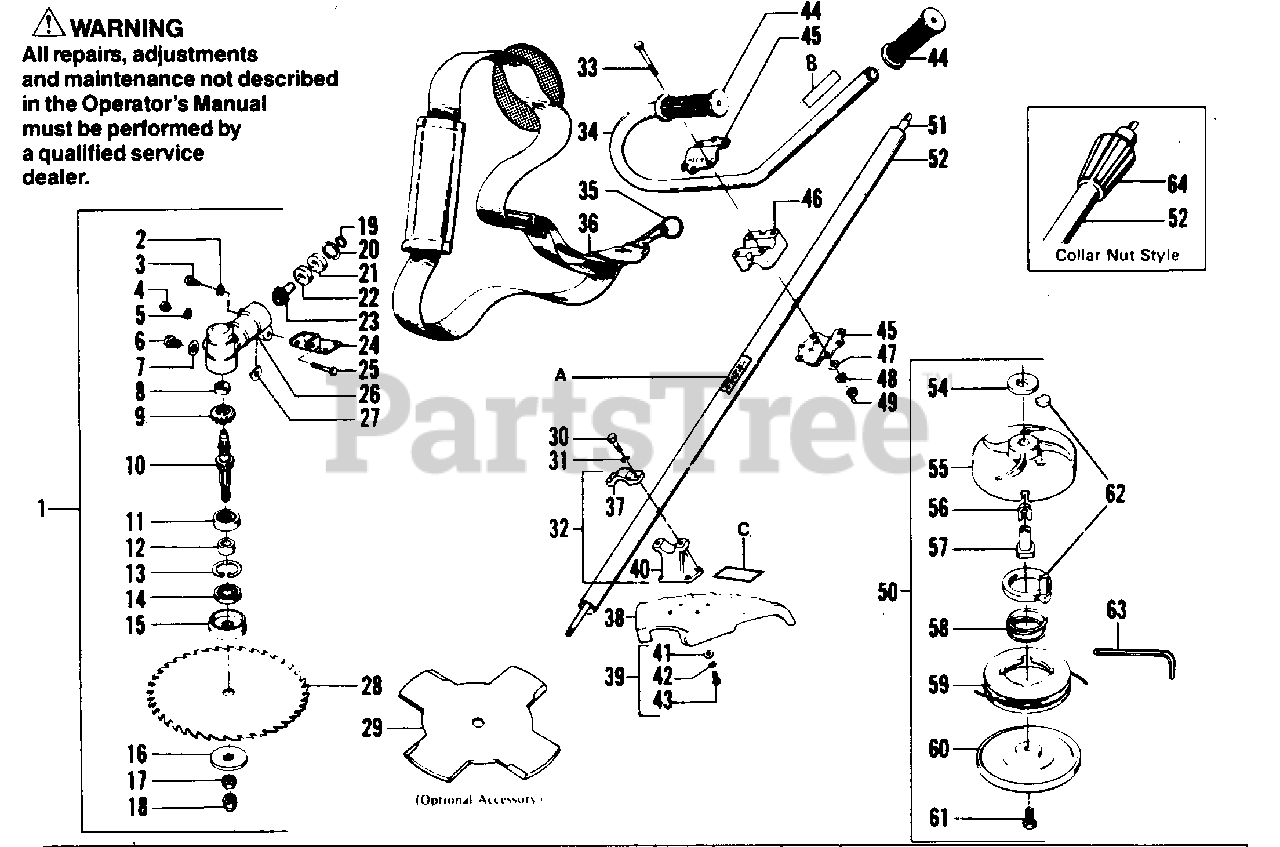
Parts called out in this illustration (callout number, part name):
1	Gear Box Ass'y w/fasteners (Inc. 2-27)
2	Lockwasher - Housing Bolt
3	Bolt - 6 x 12mm
4	Nut - 6mm - Housing (Gear Box)
5	Lockwasher - 6mm - Housing (Gear Box)
6	Oil Plug
8	Bearing - Gear Box
9	Gear - Bevel
10	Shaft - Splined Drive
11	Ball Bearing
12	Collar - Shaft
13	Snap Ring
14	Oil Seal
15	Blade Adaptor - Upper
16	Blade Adaptor - Lower
19	Snap Ring - Gear Housing
20	Snap Ring - Gear Housing Bearing
21	Bearing - Sealed Pinion Gear
22	Bearing - Pinion Gear
23	Pinion Gear
24	Bracket-Shield to Gear Box,See Service Ref. 1
25	Bolt 6 x 42mm - Housing (Gear Box)
26	Housing - Gear Box
27	Fiber - Filler Washer
28	10" Brush Blade
29	8" Weed Blade (Optional)
30	Bolt - 5 x 25mm
31	Washer - 5mm
32	Shield Mounting Bracket Ass'y (Inc. 37 & 40)
33	Bolt - #1/4 - 20 x 1 - 7/8" - Handlebar
34	Handlebar
35	Key Ring - Shoulder Strap
36	Shoulder Strap
37	Shield Mounting Bracket - Top
38	Shield w/fasteners
39	Shield Mounting Kit (Inc.41,42,43 - 4 each)
40	Shield Mounting Bracket - Bottom
41	Washer - 4mm - Flat
42	Lockwasher - 4mm
43	Screw - 4mm x 16mm
44	Grip - Handlebar
45	Handlebar Clamp
46	Handlebar Block
47	Washer - Handlebar
48	Lockwasher - Handlebar
49	Nut - #1/4 - 20
50	Cutting Head Assembly (Inc. 54-63)
51	Drive Shaft
52	48" Drive Shaft Housing w/bearings
52	Collar Nut Style (Inc.64)
52	Pinch Clamp Style
56	Line Saver
57	Drive Adaptor
59	Spool w/line
60	Cover - Cutting Head
61	Screw - #3/8 - 16 x 7/8" - Cover
62	Release Button Ass'y (Incl. Lock Ring)
63	Allen Wrench - Cutting Head
64	Collar Nut
A	Decal Handlebar Location
A	Model XR-90
A	Model XR-95,XR-100
B	Decal Handlebar Warning
B	Model XR-90
B	Model XR-95
B	Model XR-100
C	Decal Blade Rotation Warning
